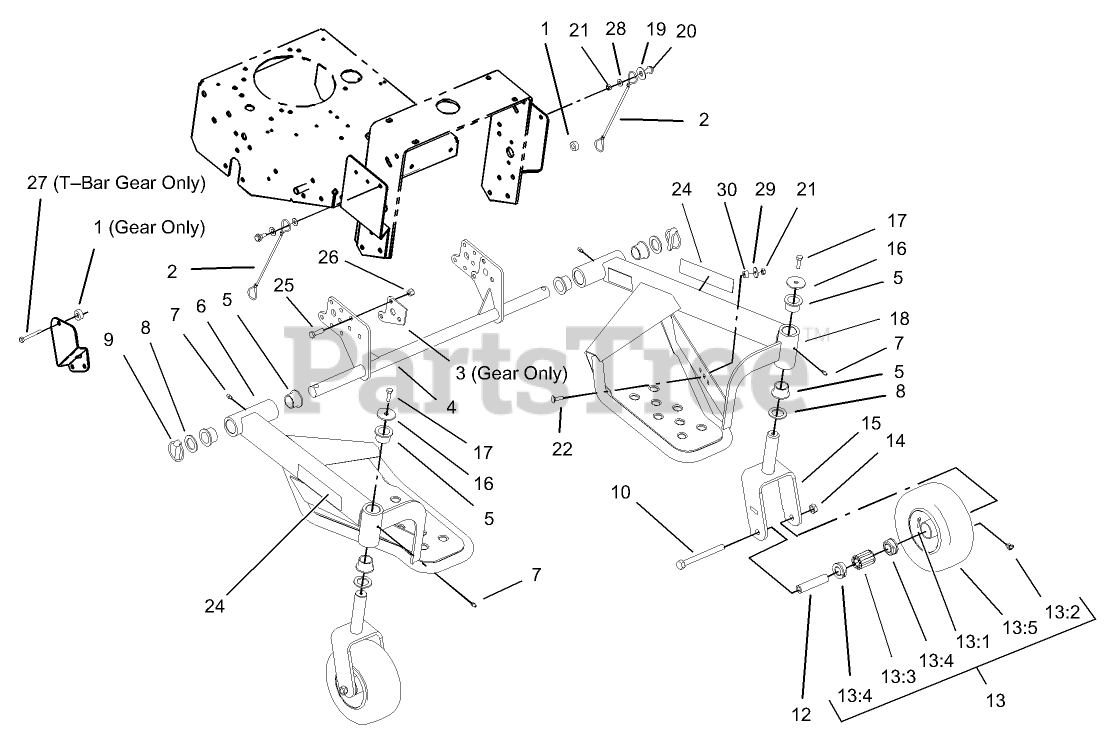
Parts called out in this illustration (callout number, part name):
1	SPACER
2	LANYARD
3	PLATE-SPACER
4	AXLE ASM
5	BUSHING
6	LH FLOOR PLATE ASM
7	FITTING-GREASE
8	WASHER-THRUST
9	PIN-LYNCH
10	SCREW-HH
12	BUSHING-SPANNER
13	CASTER WHEEL ASM
13:1	STEM-VALVE
13:2	FITTING-LUBE, 45 DEG
13:3	BEARING
13:4	BEARING-OUTSIDE
13:5	TIRE-TUBELESS
14	NUT-HEX
15	CASTOR ASM
16	WASHER-REBOUND
17	SCREW-HH
18	RH FLOOR PLATE ASM
19	WASHER-FLAT
20	BOLT-SHOULDER
21	NUT-LOCK, NI
22	BOLT-CARR
25	SCREW-HH
26	NUT-LOCK, NI
27	SCREW-HH
28	WASHER-FLAT
29	Washer-Friction
30	SPACER
